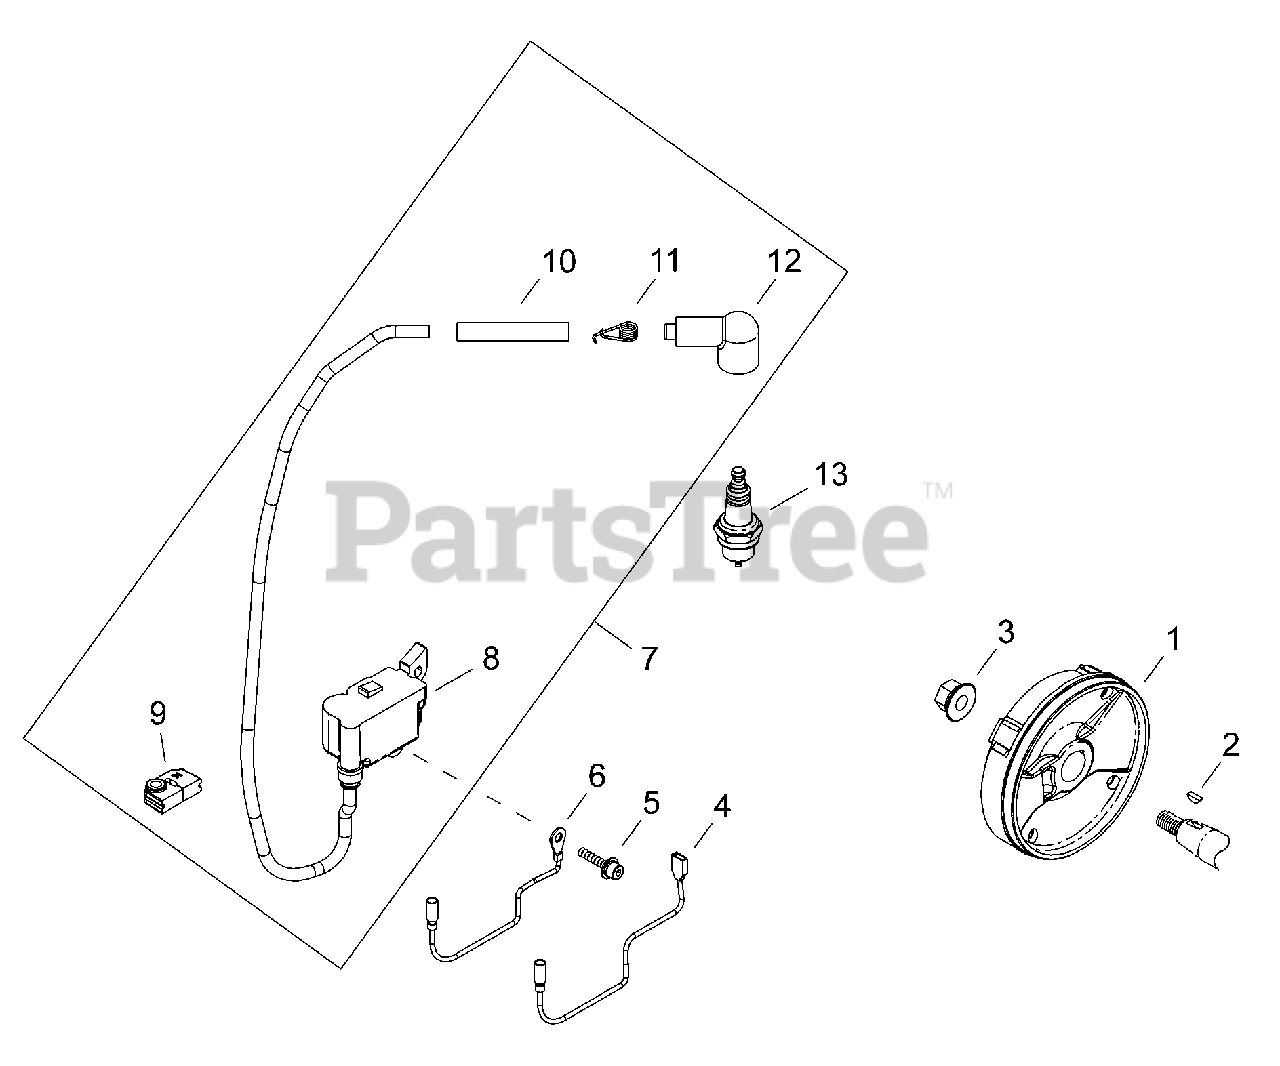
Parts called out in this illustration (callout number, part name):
1	FLYWHEEL
2	KEY, WOODRUFF 3×10
3	NUT M8
4	LEAD - IGNITION L= 170
5	BOLT M4×20
6	LEAD - GROUND
7	COIL ASSY, IGNITION
8	COIL, IGNITION
9	GROMMET
10	TUBE, INSULATOR
11	TERMINAL, SPARK PLUG
12	CAP, SPARK PLUG
13	SPARK PLUG - RCJ6Y
